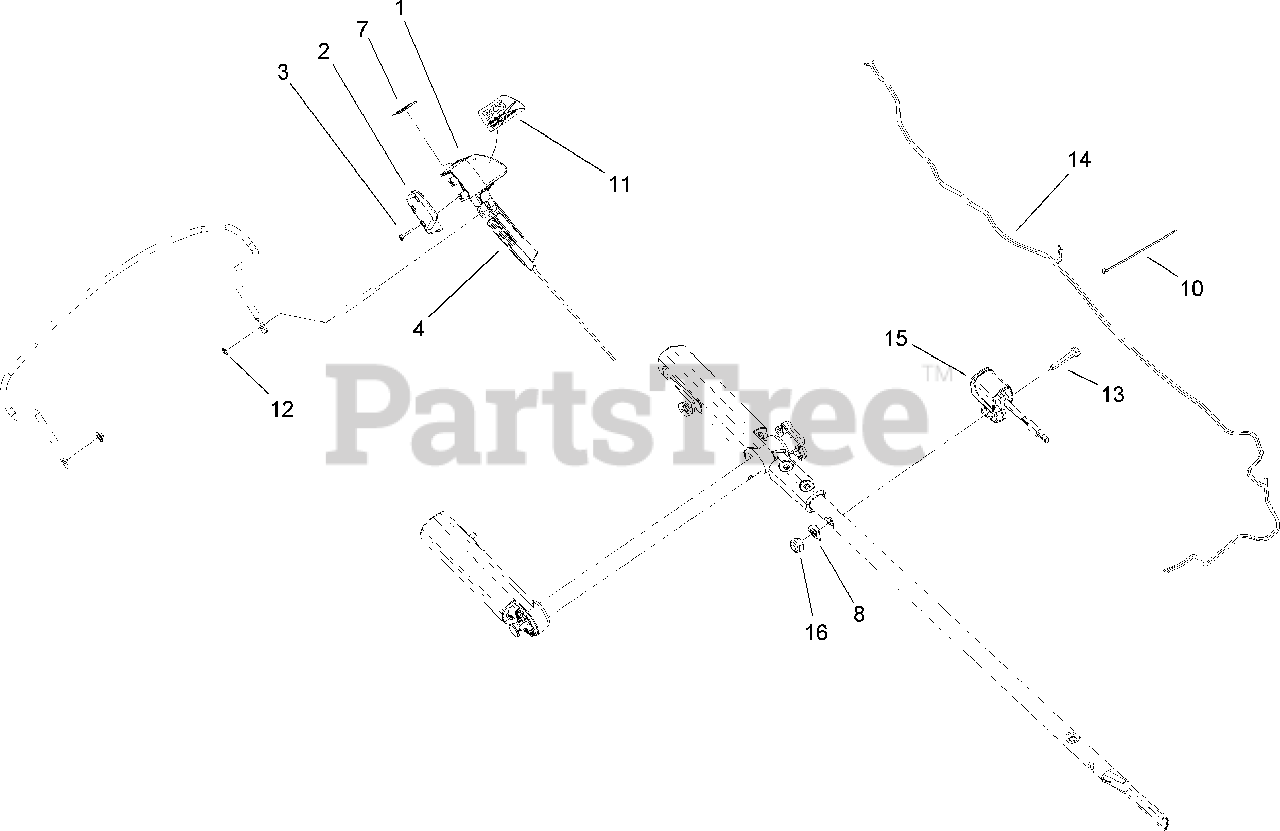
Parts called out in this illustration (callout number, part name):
1	BUTTON ASM
2	COVER-SWITCH
3	SCREW-PPH
4	CABLE-BRAKE
7	DECAL-BLADE, BBC
10	STRAP-TIE
11	DECAL-CONTROL, BLADE
12	RING-RETAINING
13	SCREW-HH
14	HARNESS-WIRE
15	SWITCH HOUSING ASM
16	NUT-LOCK, NI
